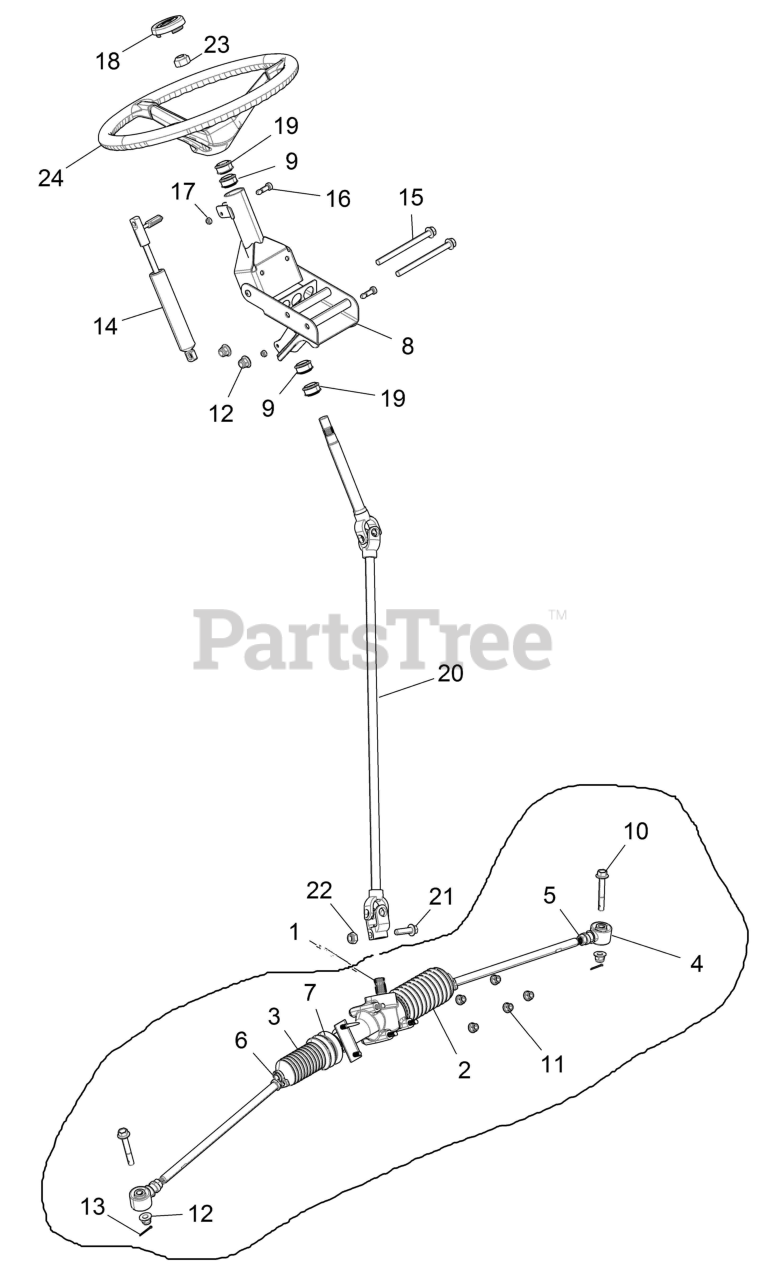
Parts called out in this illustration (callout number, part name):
1	ASM-GEAR BOX,STEERING
2	BOOT-DRIVER SIDE,RACK
3	BOOT-PASSENGER,SIDE RACK
4	ROD, END
5	NUT,JAM,LH(10)
6	CLAMP-BOOT,SMALL
7	CLAMP-BOOT,LARGE
8	ASM-TILT,STEERING,RVTD,M10,BLK
9	BEARING-STEERING
10	BOLT-M10X1.25X65,HX WASH HD
11	NUT-M8X1.25,FLG,NYLOC-OLIVE D
12	NUT-M10X1.25,FLG,NYLOC-OLIVE D
13	PIN,COTTER(10)
14	ASM-SHOCK,OIL LOCKING,MACH
15	BOLT-M10X1.25X130,HXFLG-OLIVED
16	BOLT-SHOULDER,M8-15,M6X1.0-BLK
17	NUT,NYLOK(10)
18	CAP, STEERING WHEEL
19	BUSHING-STEERING
20	SHAFT-STEERING,UPPER/LOWER
21	SCR-M10X1.50X35 HX/FL
22	NUT-NY INS,M10X1.5,HEX,ZINC,YW
23	NUT-HEX-M16X2, 8 ZC NYL
24	WHEEL-STEERING,15"
